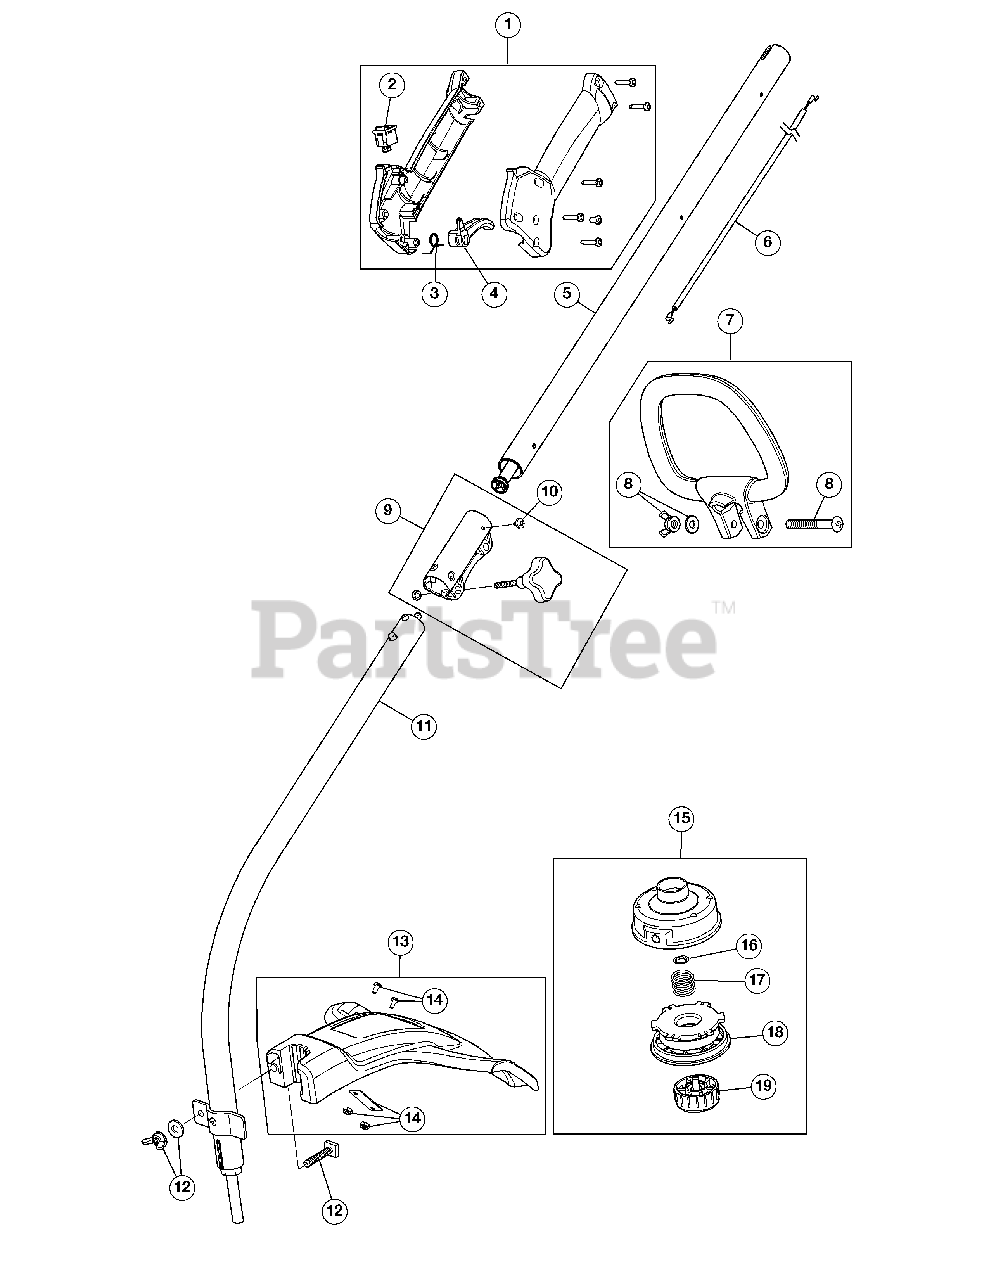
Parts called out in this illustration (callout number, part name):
1	Throttle Housing Assembly (Incl. 2 - 4)
2	Switch Assembly
3	Throttle Trigger
4	Throttle Trigger Spring
5	Upper Shaft Housing Assembly
6	Throttle Cable
7	D-Handle (Incl. 8)
8	D-Handle Hardware Assembly
9	Split Boom Coupler (Incl. 10)
10	Anti-Rotation Screw
11	Lower Shaft Housing Assembly
12	Shield Mounting Hardware
13	Shield Assembly (Incl. 14)
14	Blade Assembly
15	Outer Spool Assembly (Incl. 16)
16	Retainer
18	Inner Reel
19	Bump Head Knob Assembly
